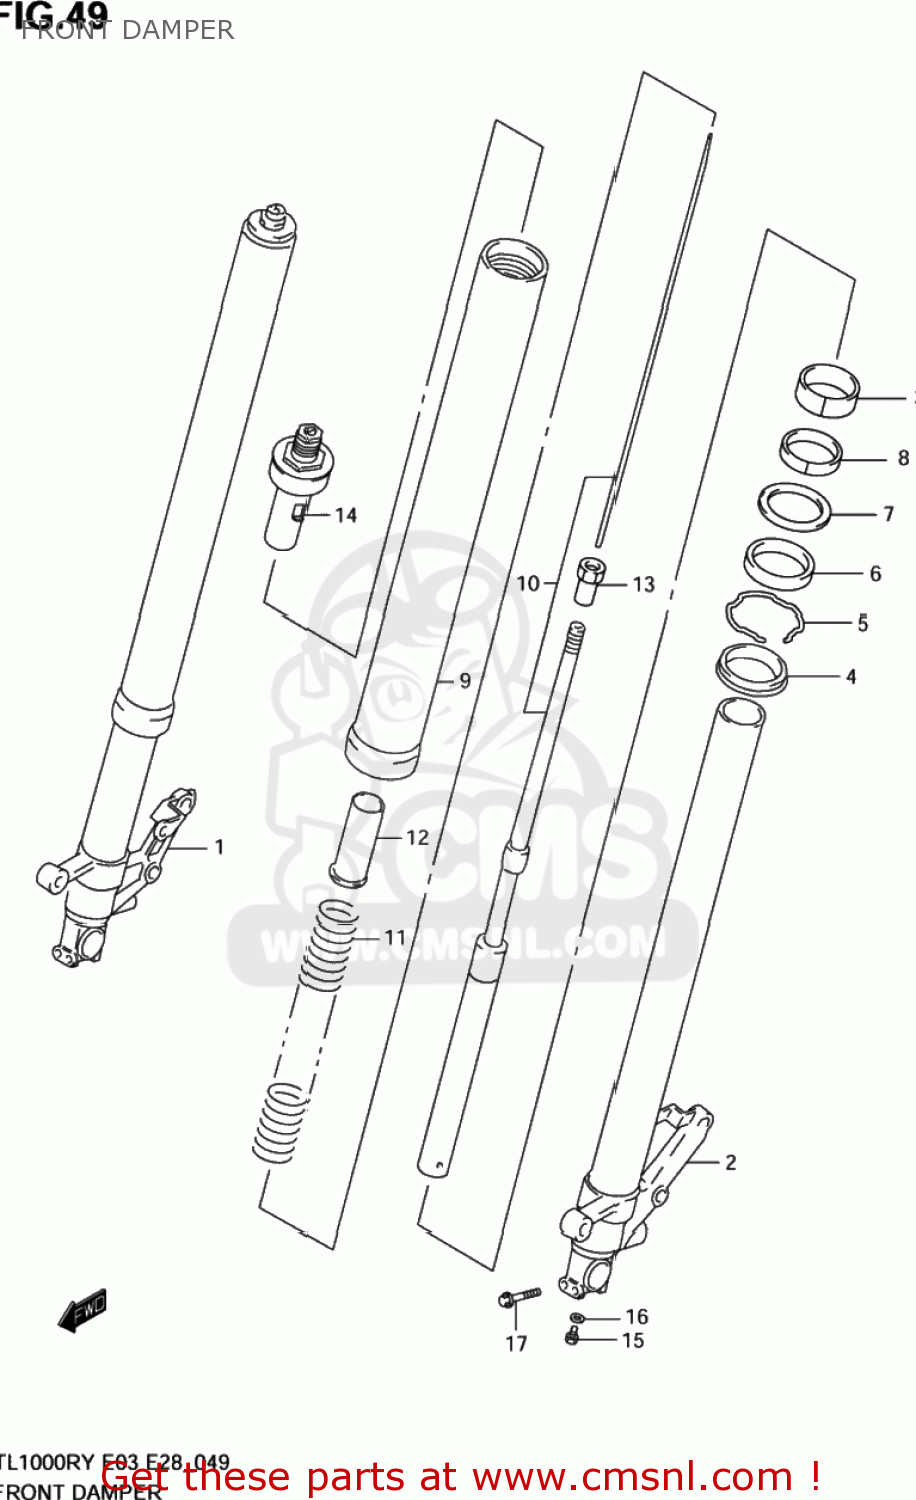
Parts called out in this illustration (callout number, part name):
1	TUBE,INNER,R
2	TUBE,INNER,L
3	PISTON
4	SEAL,DUST
5	RING,STOPPER
6	SEAL,OIL
7	WASHER
8	METAL,SLIDE
9	TUBE,OUTER
10	CYLINDER
11	SPRING,FR
12	SPACER,SPRING
13	NUT,PISTON ROD
14	CAP,FR FORK
15	BOLT,OIL LOCK PIECE,12X22
16	GASKET,CYLINDER (NAS)
17	BOLT
